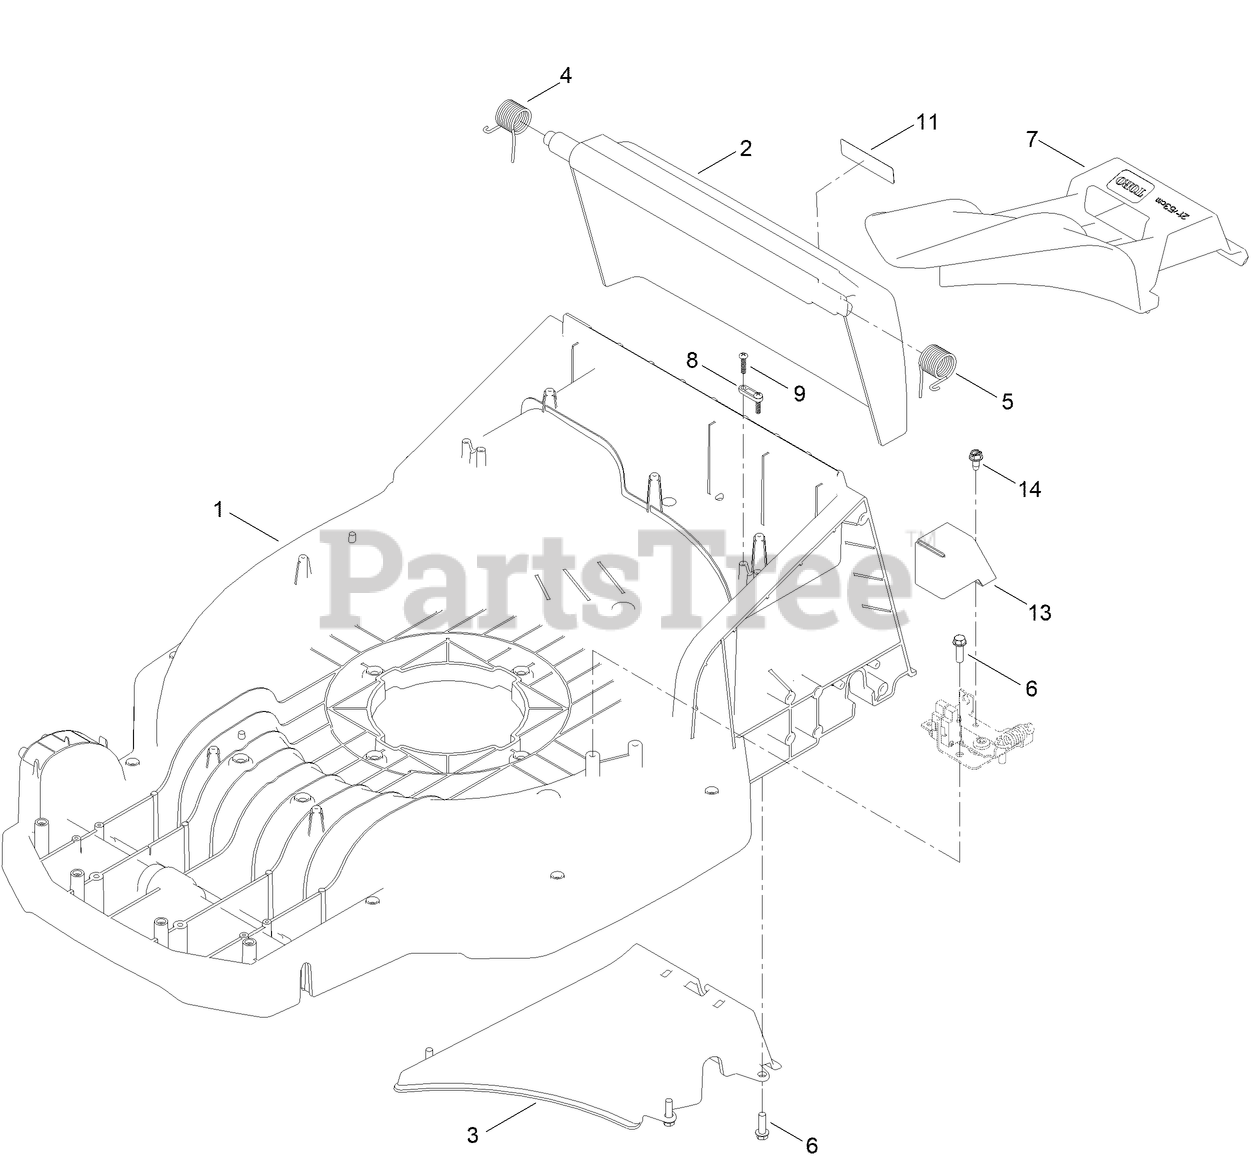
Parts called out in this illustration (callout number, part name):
1	DECK-PLASTIC, 21"
2	ASM-REAR DOOR, IN-MOLD (60V)
3	RAMP-DISCHARGE
4	SPRING-TORSION, RH
5	SPRING-TORSION, LH
6	SCREW-HWH
7	PLUG-DISCHARGE
8	CLAMP-HARNESS
9	SCREW-PPH
11	DECAL-PROP 65, SHORT, TRILINGUAL
13	COVER-SWITCH
14	SCREW-HWH
